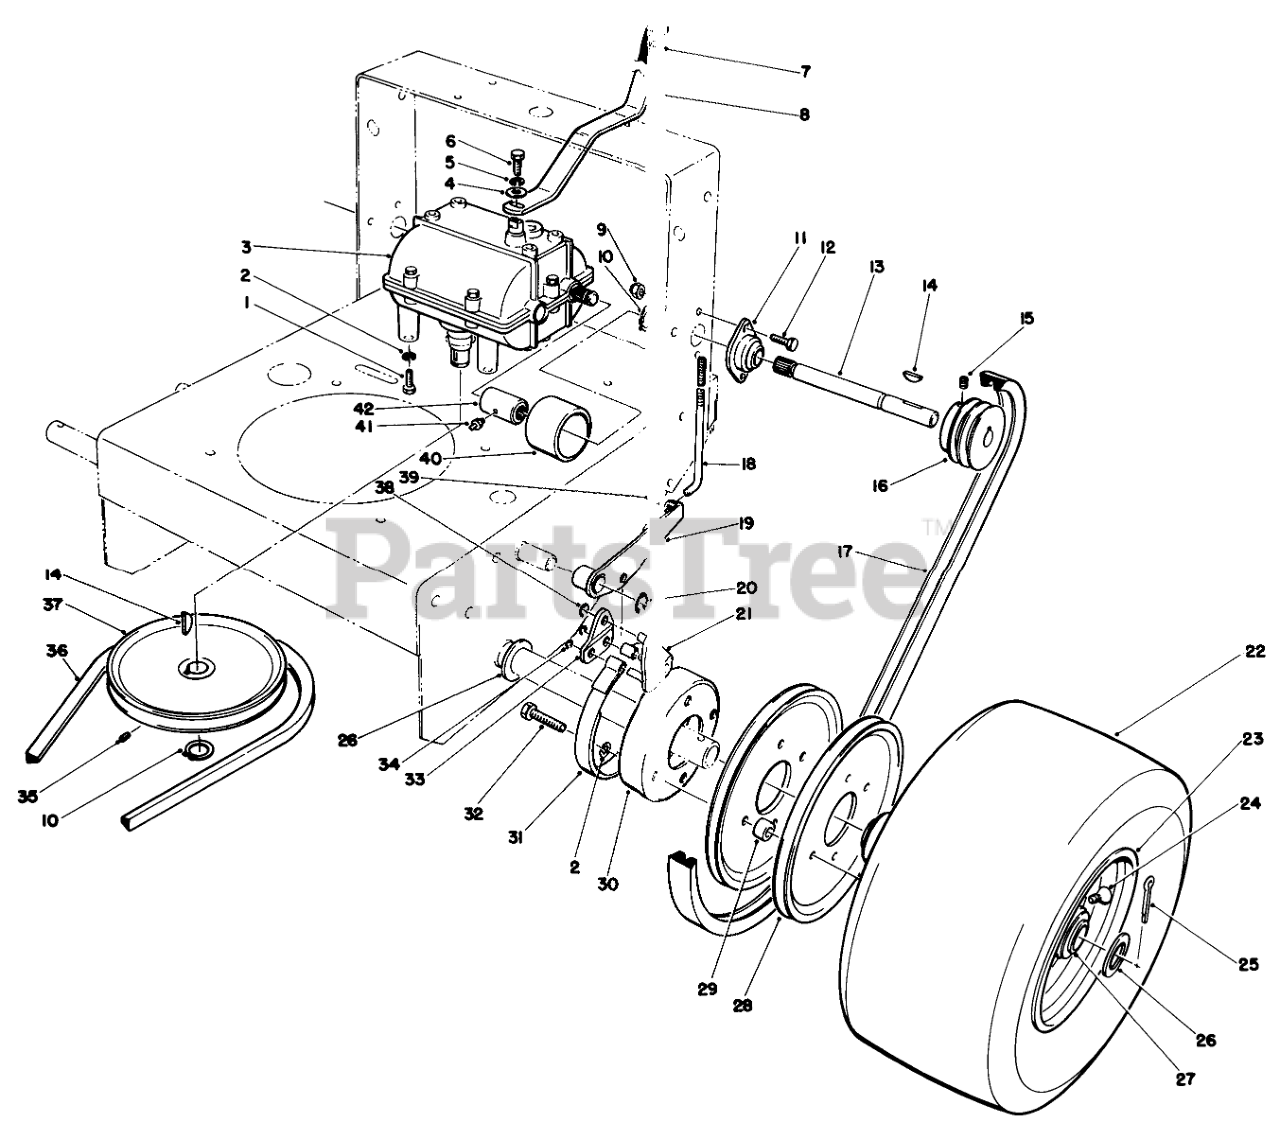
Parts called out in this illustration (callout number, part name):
1	SCREW-HH
2	WASHER-LOCK
3	Transmission
4	SPACER
5	WASHER-LOCK
6	SCREW-HH
8	LEVER-SHIFT
9	NUT-LOCK, NI
10	RING-SNAP, EXTERNAL
11	BEARING-EXTERNAL SHAFT
12	SCREW-HH
13	SHAFT-EXTENSION, RH
14	Key-Non Roc
15	SCREW-SET, HSH
16	Pulley-Drive
17	V-BELT
18	ROD-BRAKE
19	Brake Arm-LH
20	RING-RETAINING
21	LINK-Brake
23	Rim
24	STEM-VALVE
25	PIN-COTTER
26	WASHER-WHEEL
27	BEARING-WHEEL
28	Pulley-Wheel
29	SPACER-PULLEY
30	Drum-Brake
31	BAND-BRAKE
32	SCREW-HH
33	Plate-Link
34	RING-RETAINING
35	SCREW-SET, HSH
36	V-BELT
37	PULLEY-DRIVEN
38	RING-RETAINING, EXTERNAL
39	PIN-COTTER
40	GUARD-COUPLER
41	FITTING-STRAIGHT
42	COUPLER
